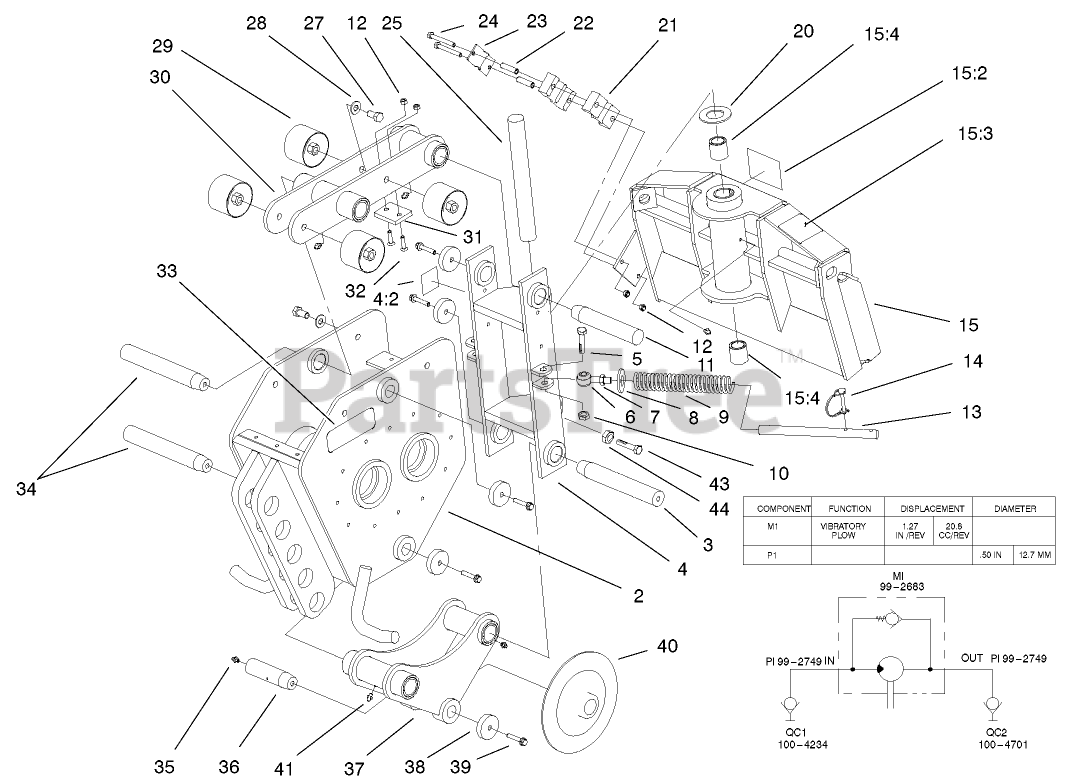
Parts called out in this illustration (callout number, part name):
2	FRAME ASM
3	PIN-TAPERED
4	CLEVIS ASM
4:2	DECAL-WARNING
5	SCREW-HH
6	ROD END
7	NUT-JAM
8	WASHER
9	Spring
10	NUT-HEX
11	PIN-TAPERED
12	NUT-LOCK, NI
13	ROD-THREADED
14	PIN-HITCH
15	Q-TACH ASM
15:2	DECAL
15:3	DECAL-DANGER
15:4	BUSHING-TENSION
20	WASHER
21	CLAMP
22	SPACER
23	CLAMP-DRAIN, CASE
24	SCREW-HH
25	PIN-PIVOT
27	SCREW-HH
28	WASHER-FLAT
29	MOUNT-SANDWICH
30	LINK ASM
31	PAD-STOP
33	DECAL-SITEWORKS
34	PIN-TAPERED
35	FITTING-GREASE
36	PIN-TAPERED
37	LINK ASM
38	WASHER-CLUTCH
39	SCREW-HHF
40	COULTER
41	FITTING-GREASE, 90 DEG
43	SCREW-HH
44	NUT-LOCK, NI
